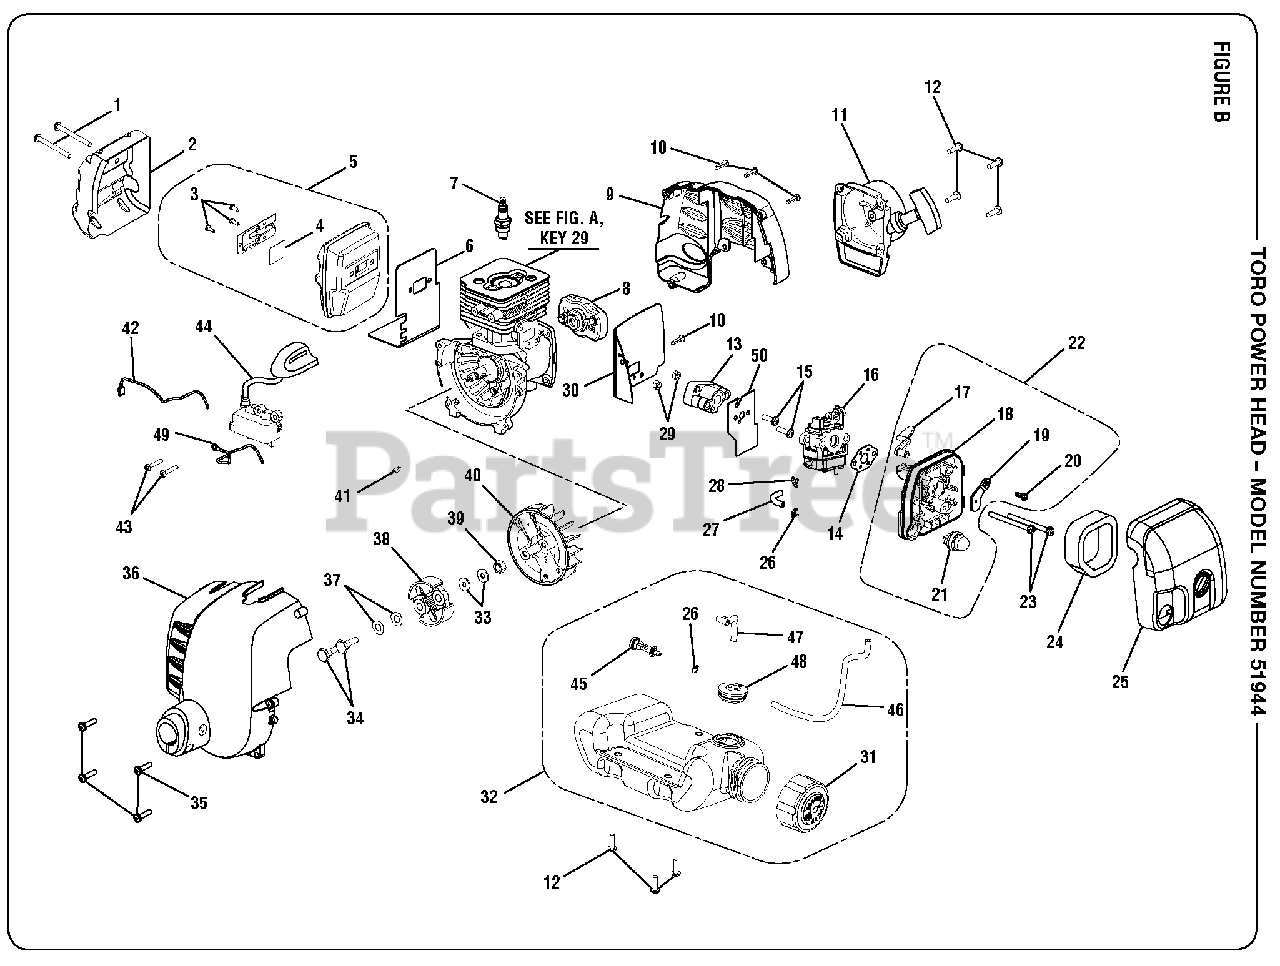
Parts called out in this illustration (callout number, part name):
1	Screw (M5 x 50 mm, Torx Slotted Recessed Pan Hd.)
2	Heat Shield
3	Screw (6-20 x 1/4 in., Pan Hd.)
4	Screen
5	Muffler Assembly (Inc. Key Nos. 3-4)
6	Muffler Gasket
7	Spark Plug (RCJ6Y)
8	Starter Cup
9	Rear Engine Housing
10	Screw (M4 x 16 mm, Torx Recessed Pan Hd.)
11	Starter Recoil Assembly
12	Screw (M5 x 16 mm, Torx Slotted)
13	Heat Dam Insulator
14	Carburetor Gasket
15	Screw (M5 x 31 mm, Torx Slotted Recessed Pan Hd.)
16	Carburetor Assembly
17	Choke Lever
18	Carburetor Plate
19	Choke Plate
20	Screw (M4 x 12 mm, Slotted Recessed Pan Hd.)
21	Primer Assembly
22	Filter Housing Assembly (Inc. Key Nos. 17-21)
23	Screw (M5 x 60 mm, Slotted Recessed Pan Hd. Machine)
24	Air Filter (Element)
25	Cover Assembly
26	Hose Clip
27	Fuel Line (45 mm)
28	Hose Clip
29	Hex Nut (M5 x .8 mm)
30	Insulator Gasket
31	Fuel Cap Assembly
32	Fuel Tank and Cap Assembly (Inc. Key Nos. 31 and 45-48)
33	Washer
34	Clutch Screw
35	Screw (M5 x 20 mm, Torx Slotted Recessed Pan Hd.)
36	Front Housing Assembly
37	Curved Washer
38	Clutch Assembly
39	Rotor Nut
41	Woodruff Key (10 mm x 3 mm)
42	Lead Wire (Black)
43	Screw (M4 x 22 mm, Torx Slotted Recessed Pan Hd.)
44	Coil Boot Assembly
45	Fuel Filter
46	Fuel Line (150 mm)
47	Fuel Line (118 mm)
48	Grommet
49	Lead Wire (Red)
